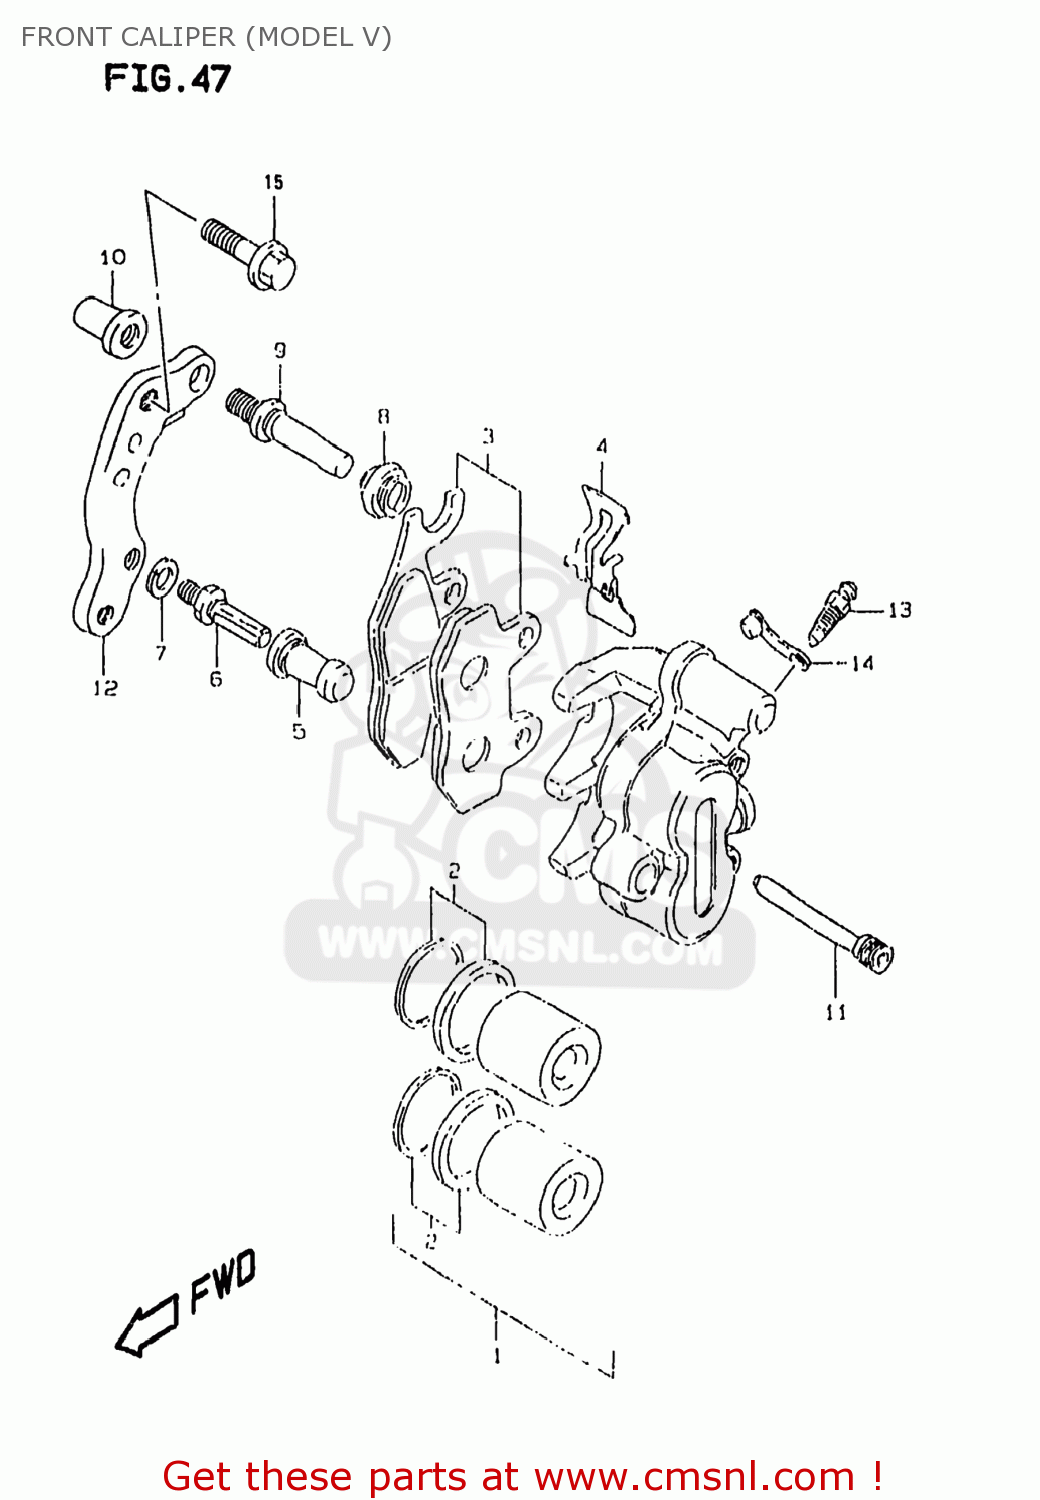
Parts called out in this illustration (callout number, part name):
1	PISTON SET
2	SEAL SET,PISTON
3	PAD SET (NAS)
4	SPRING
5	BOOT
6	BOLT,PIN
7	WASHER,WAVE
8	BOOT
9	PIN,SLIDE
10	NUT
11	PIN,HOLDER
12	BRACKET
13	BLEEDER
14	CAP,BLEEDER
15	BOLT(8X24)
